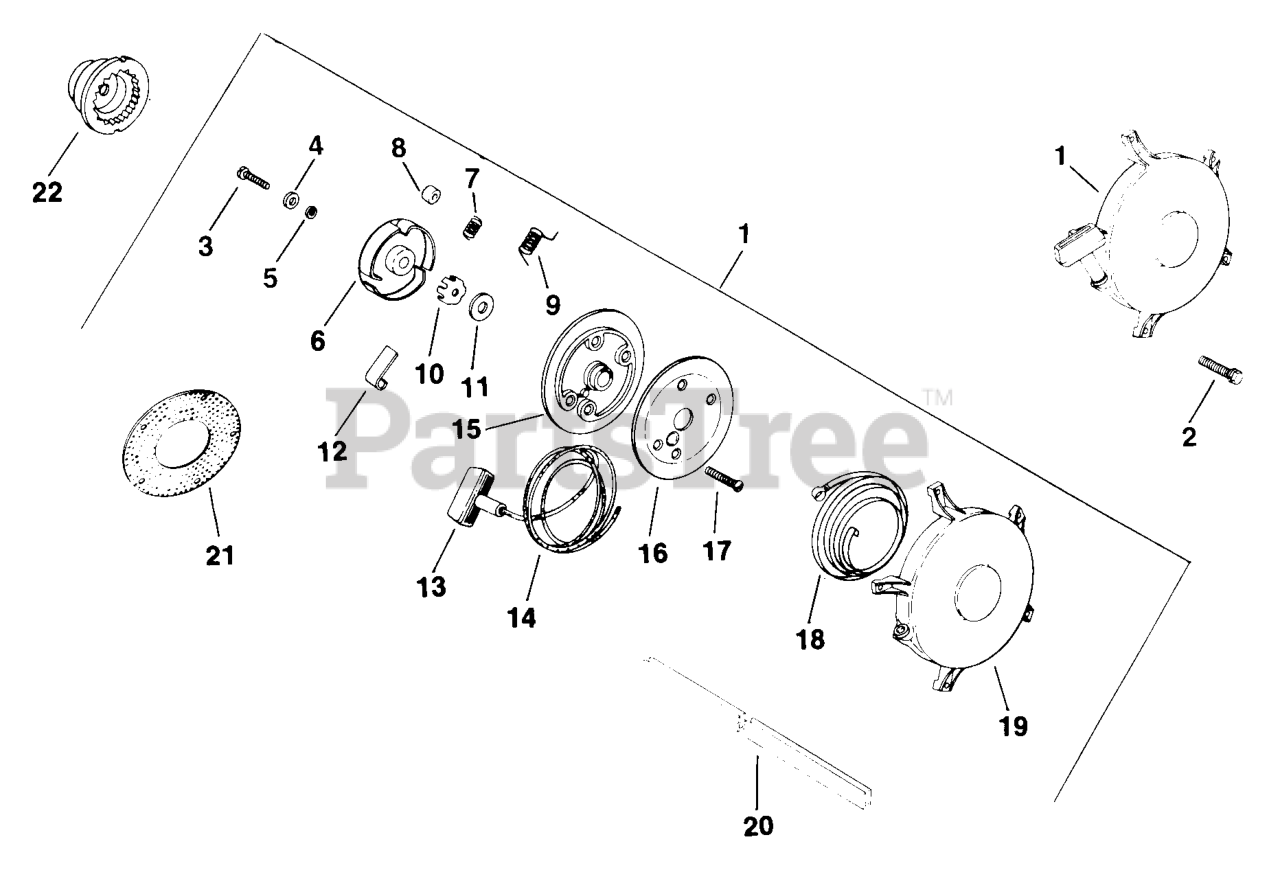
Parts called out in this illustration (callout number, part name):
1	STARTER - DISCONTINUED
1	STARTER
4	WASHER - DISCONTINUED
6	RETAINER
7	SPRING - DISCONTINUED
8	SPACER
12	DOGS - DISCONTINUED
13	HANDLE - USE 25 166 01
19	HOUSING - DISCONTINUED
21	BAFFLE, HEAD - (#DSC)
22	CUP - DISCONTINUED
22	CUP, DRIVE - DISCONTINUED
X-22-22-S	WASHER, EXT TOOTH LOCK #10
X-70-3-S	NUT, MACH SCREW #10-32 GRD 2 USE 25 100 18-S
X-97-2-S	SCREW, IND SLT HD 10-32X1/2" USE 24 086 55-S
